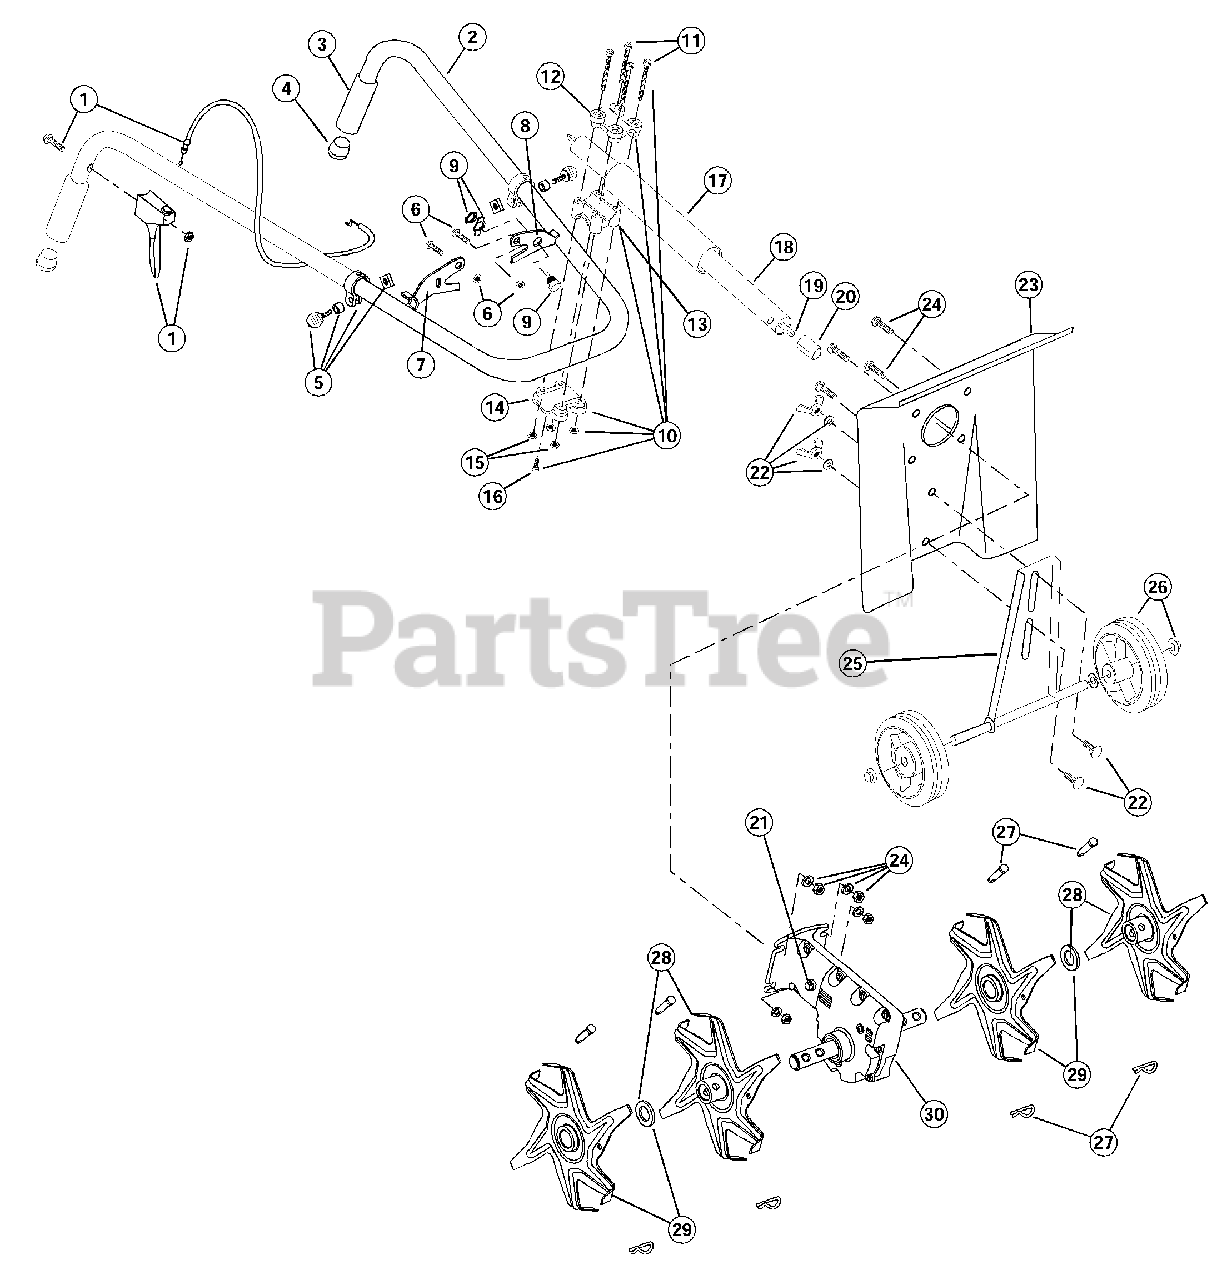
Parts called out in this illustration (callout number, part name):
1	Throttle Trigger and Cable Assembly
2	Handle Bar w/Clamp Assemblies
4	Tube Closure
5	Clamp Assembly
6	Engine Bracket Mounting Hardware
7	Engine Mount Bracket, R.H.
8	Engine Mount Bracket, L.H.
9	Switch Assembly
10	Handle Bracket Assembly
12	Upper Handle Clamp
13	Middle Handle Clamp
14	Lower Handle Clamp
16	Anti-Rotation Screw
18	Drive Shaft Housing Assembly
19	Flexible Drive Shaft
20	Retainer Sleeve
21	Sleeve Retainer Bolt
22	Wheel Bracket Mounting Hardware
24	Guard Mounting Hardware
25	Wheel Bracket Assembly
26	Wheel Assembly
27	Tine Fastener Assembly
28	Tine Assembly (Left Outer or Right Inner)
29	Tine Assembly (Left Inner or Right Outer)
30	Gear Box Assembly
